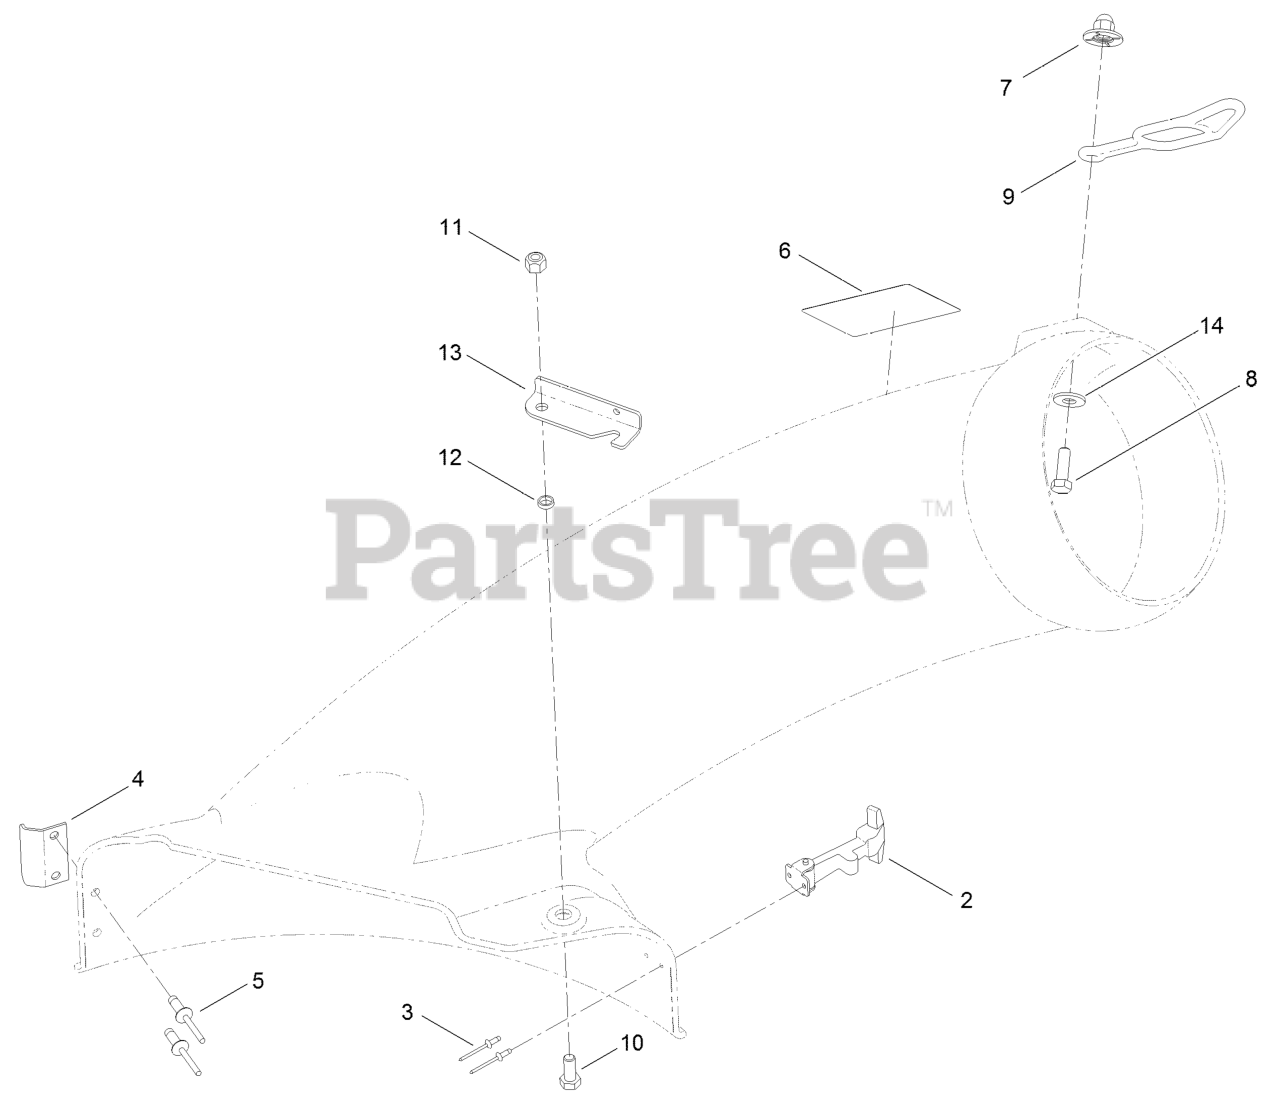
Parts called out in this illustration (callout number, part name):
2	HANDLE ASM
3	RIVET-POP
4	BRACKET-ELBOW
5	RIVET-BLIND
6	DECAL-DANGER
7	NUT-IMPELLER
8	SCREW-HH
9	RETAINER-DUCT
10	SCREW-HH
11	NUT-LOCK, NI
12	BUSHING
14	WASHER-FLAT
